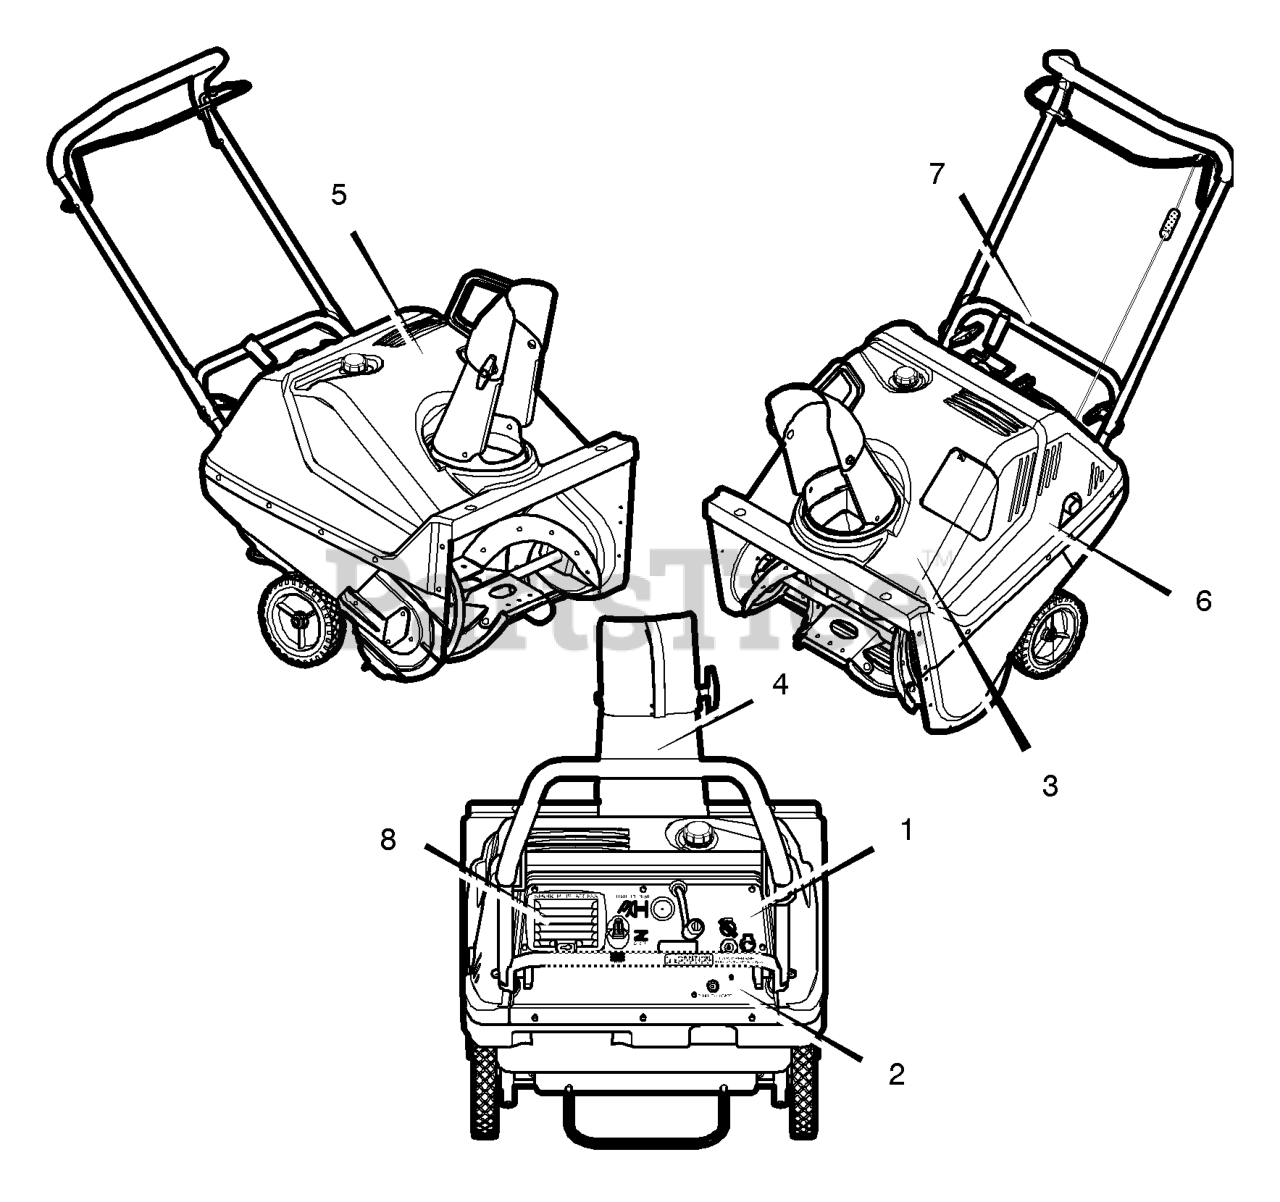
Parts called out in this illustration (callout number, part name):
1	Decal, Panel - 22" ES CANADA
2	Decal, Push To Start
3	Decal, Danger Auger
4	Decal, Danger Chute
5	Decal, 5hp 22" CRAFTSMAN
6	Decal, Danger Muffler
7	Decal, Auger Control
8	Decal, Spark Plug Access
